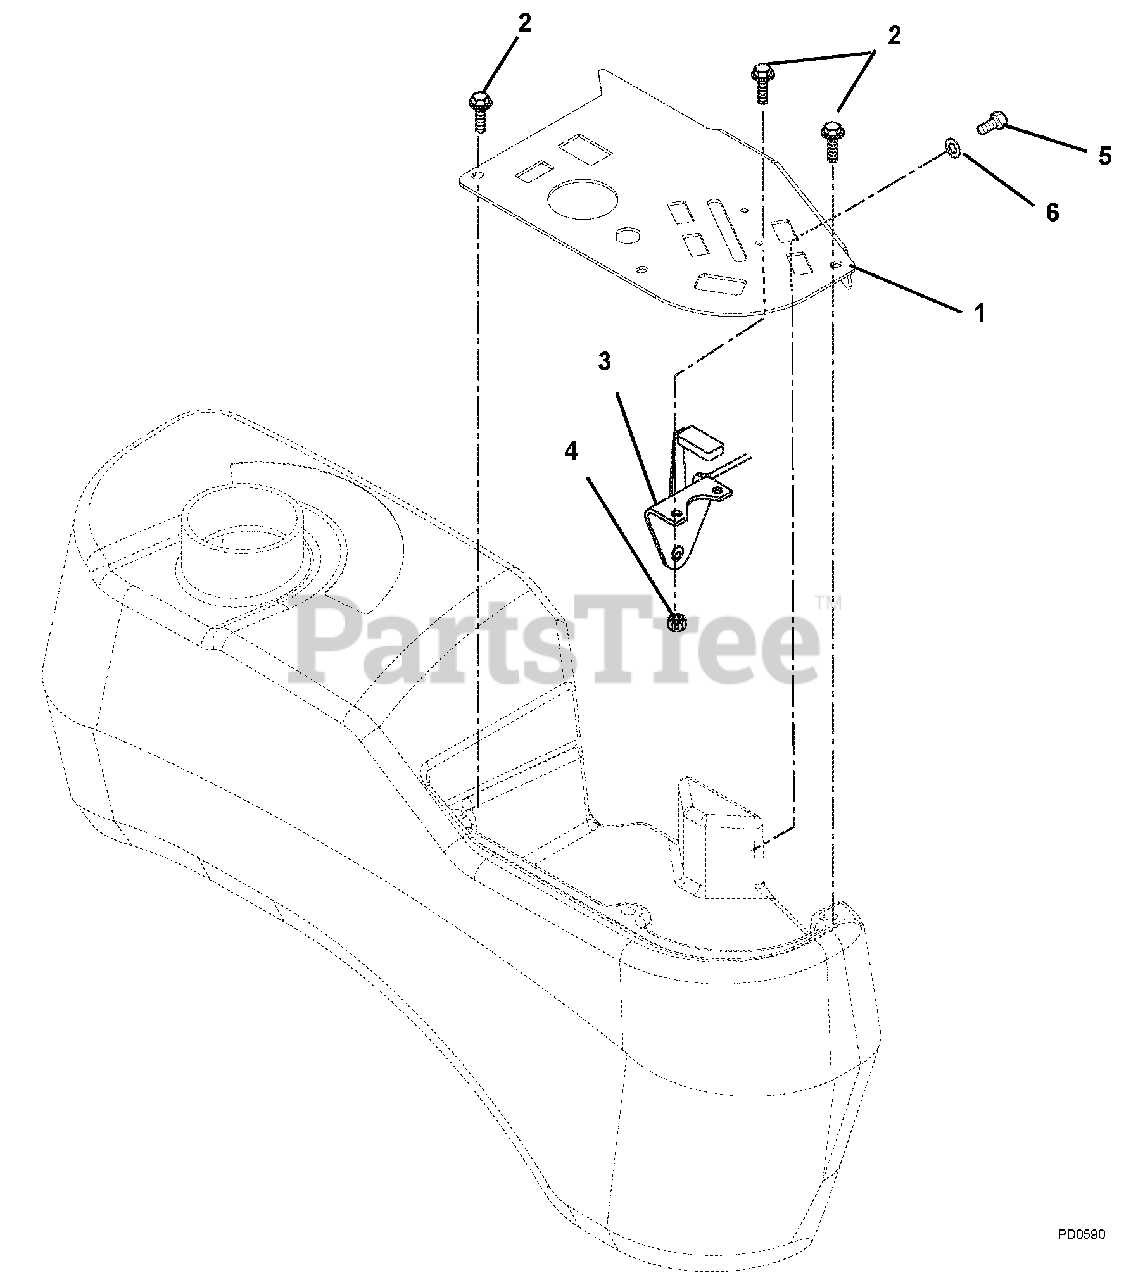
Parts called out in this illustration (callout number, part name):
1	Panel, Control
2	Screw, Machine 10-24 x .50 Hex Washer Head Stainless
3	Throttle, Control
4	Nut, Locking Nylon 10-24 With Insert
5	Bolt, Hex .31-18 x .75 Grade 5
6	Washer, Flat Steel .38 x .875 x .083
